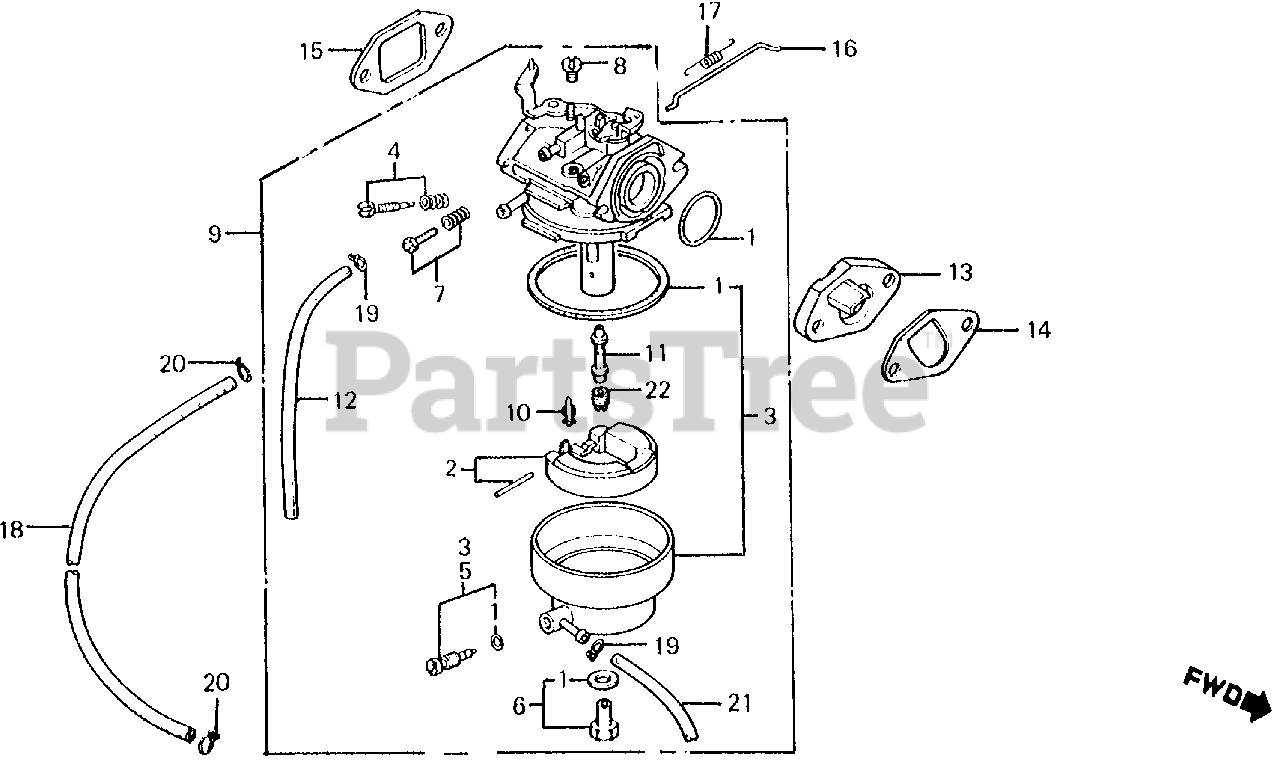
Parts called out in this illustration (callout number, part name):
1	GASKET SET
3	CHAMBER SET, FLOAT (NOT AVAILABLE)
4	SCREW SET A
5	SCREW SET, DRAIN
6	SCREW SET B
7	SCREW SET B (NOT AVAILABLE)
8	SCREW, PLUG
9	CARBURETOR ASSY.
10	VALVE, FLOAT
11	NOZZLE, MAIN (NOT AVAILABLE)
12	TUBE, AIR VENT
13	INSULATOR, CARBURETOR (NOT AVAILABLE)
14	GASKET, INSULATOR
15	GASKET, AIR CLEANER
16	ROD, GOVERNOR (NOT AVAILABLE)
17	SPRING, THROTTLE RETURN
18	BULK HOSE, FUEL (4.5X3000) (4.5X400)
19	CLIP, TUBE (B6.5)
20	CLIP, TUBE (D8.5)
21	BULK HOSE, VINYL (4X7X8000) (4X7X160)
22	JET, MAIN (#52)
22	JET, MAIN (#55)
22	JET, MAIN (#58)
